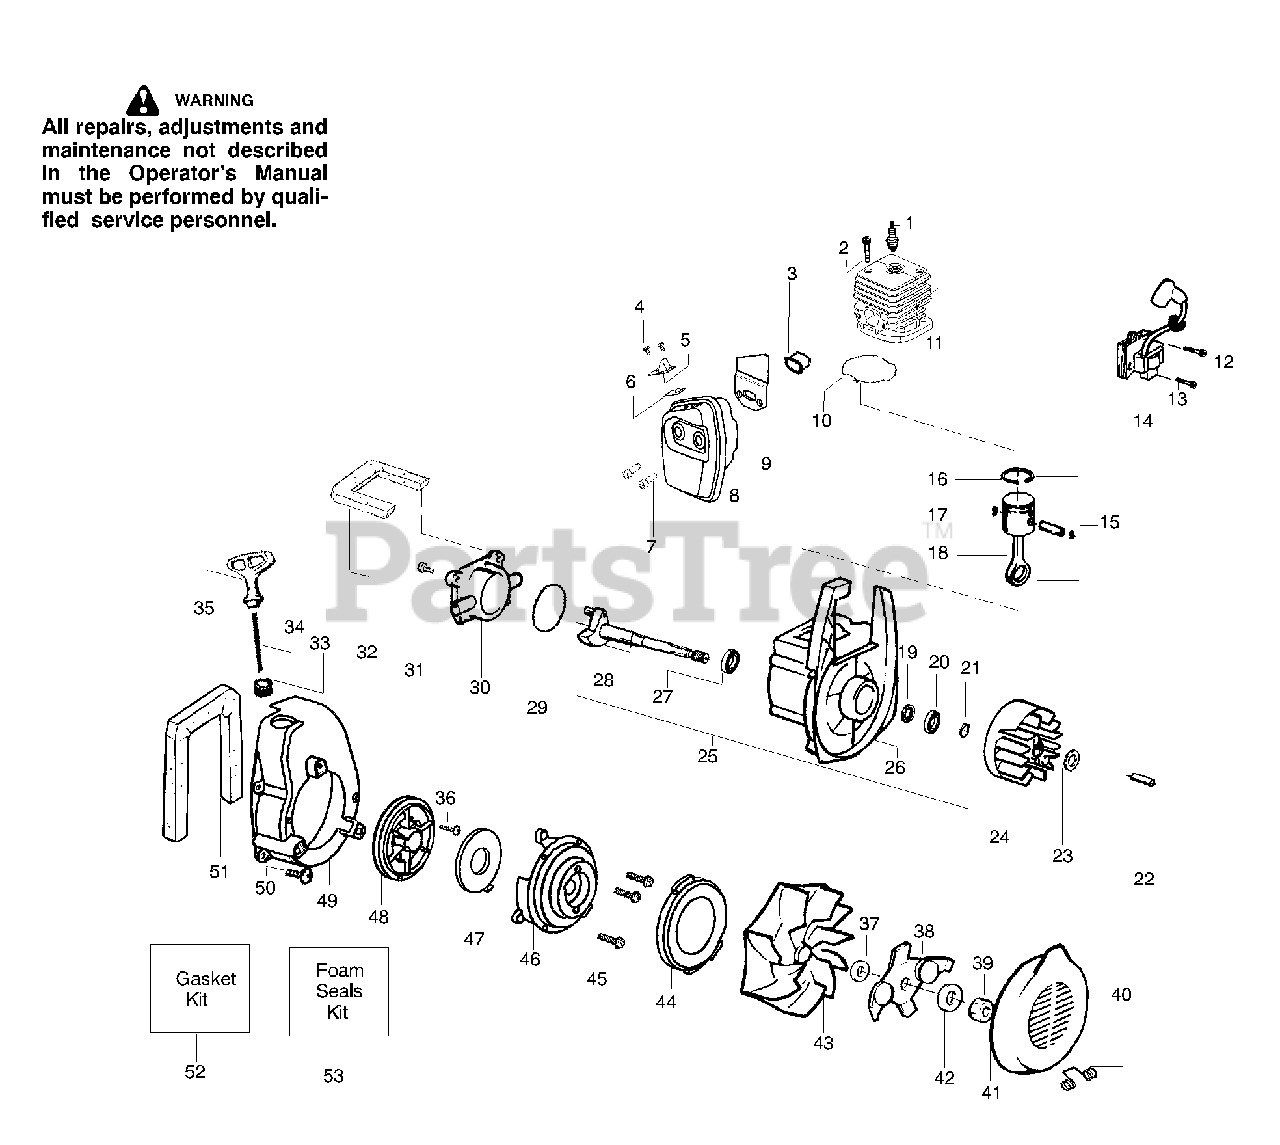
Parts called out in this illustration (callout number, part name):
1	Spark Plug (RCJ-6Y)
3	Insulator-Heat
5	Deflector-Muffler
6	Kit-Spark Screen(incl. #4)
7	Screw-Muffler-Internal
8	Kit-Muffler (incl. 4-6,7,9)
9	Gasket-Baffle (kit)
10	Gasket-Cylinder (kit)
11	Kit-Cylinder
12	Grommet-Ign. Module
13	Screw-Ignition Module
14	Module-Ignition
15	Kit-Piston
16	Ring-Piston
17	Retainer-Piston Pin
18	Assy-Connecting Rod
19	Seal-Crankcase
20	Bearing-Outer
21	Retainer Ring-C’chaft
22	Spacer-Flywheel
24	Assy-Flywheel
25	Assy-Crankcase/Crankshaft
26	Assy-Crankcase
27	Bearing-Inner
28	Assy-Crankshaft
29	O-ring-C/case (kit)
30	Cover-Crankcase
31	Screw
32	Foam-219mm (kit)
33	Eyelet-Flange
34	Kit-Rope
35	Handle-Starter
36	Screw-Rope
37	Washer-Belleville
38	Assy-Mulch Blade (BV1800 Only)
40	Spring-Return Cover
41	Door-Inlet
42	Washer (BV1650 only)
43	Kit-Impeller Assy
44	Seal-Ring
46	Housing-Pulley
47	Spring-Starter
48	Kit-Starter Pulley
49	Housing-Fan
50	Screw
51	Foam-365mm (kit)
52	Kit-Gasket
53	Kit-Foam Seals
